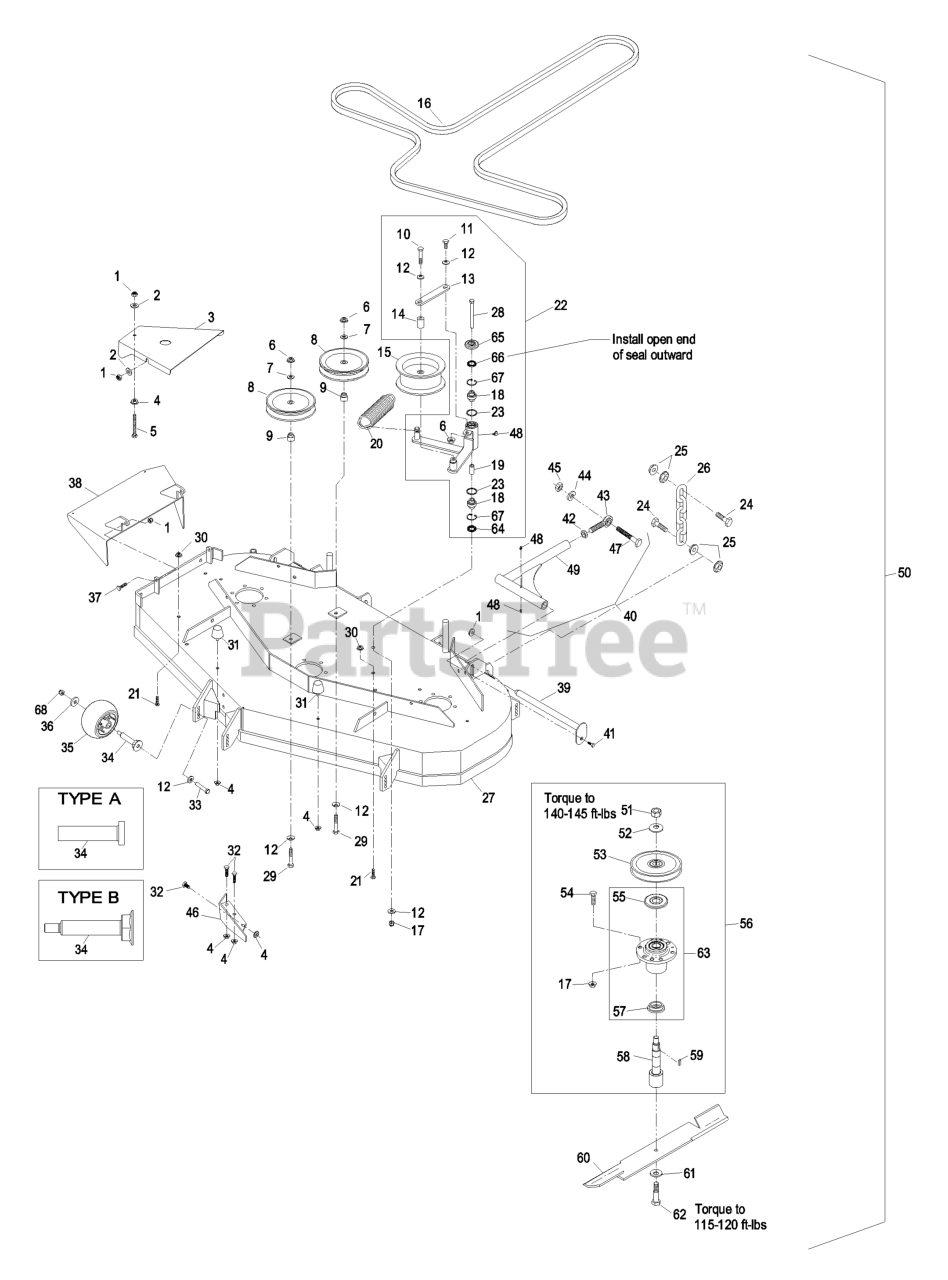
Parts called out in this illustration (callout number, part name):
1	NUT-LOCK, NI
2	WASHER-FLAT
3	SHIELD,BELT
5	BOLT,TAP HH
6	NUT-HHF, WHIZ
7	WASHER-FLAT
8	PULLEY-IDLER
9	BUSHING-IDLER
10	SCREW-HH
11	SCREW-HH
12	WASHER-BELLEVILLE
13	PLATE,GUIDE BELT (PLTD)
16	BELT,BLADE DRIVE
17	NUT-LOCK, NI
18	BEARING-SPHERICAL
21	SCREW-HH
22	KIT,DECK IDLER LHP/LCT
24	SCREW-HH
26	CHAIN-LIFT, DECK
28	SCREW-HH
29	SCREW-HH
31	BUMPER-RUBBER
32	SCREW-HH
33	SCREW-HH
34	BUSHING-ROLLER
35	ROLLER-SCALP, ANTI
37	SCREW-HH
38	WLD,DISCHARGE CHUTE
39	PIN-STRUT
40	STRUT ASM
41	SCREW-HH
42	NUT-HEX
43	BALLJOINT-SPHERICAL
44	WASHER-LOCK
45	NUT-HEX
46	WLD,BAFFLE DISCHARGE
48	FITTING-GREASE
50	Deck Complete Service
51	NUT-HH
53	SHEAVE,6.13 EOD
54	SCREW-HH
55	GUARD-BEARING, TOP
56	ASM, CUTTER HSG 52
57	SPACER-GUARD, BOTTOM
58	SPINDLE,LHP
59	KEY-RECTANGLE
61	WASHER-BLADE BOLT, HEAVY
62	SCREW-CAP
63	KIT, CUTTER HOUSING
64	SEAL-LIP, DOUBLE
65	GUARD-TOP
66	SEAL-LIP, SINGLE
67	RING-SNAP
68	NUT-HHF, WHIZ
